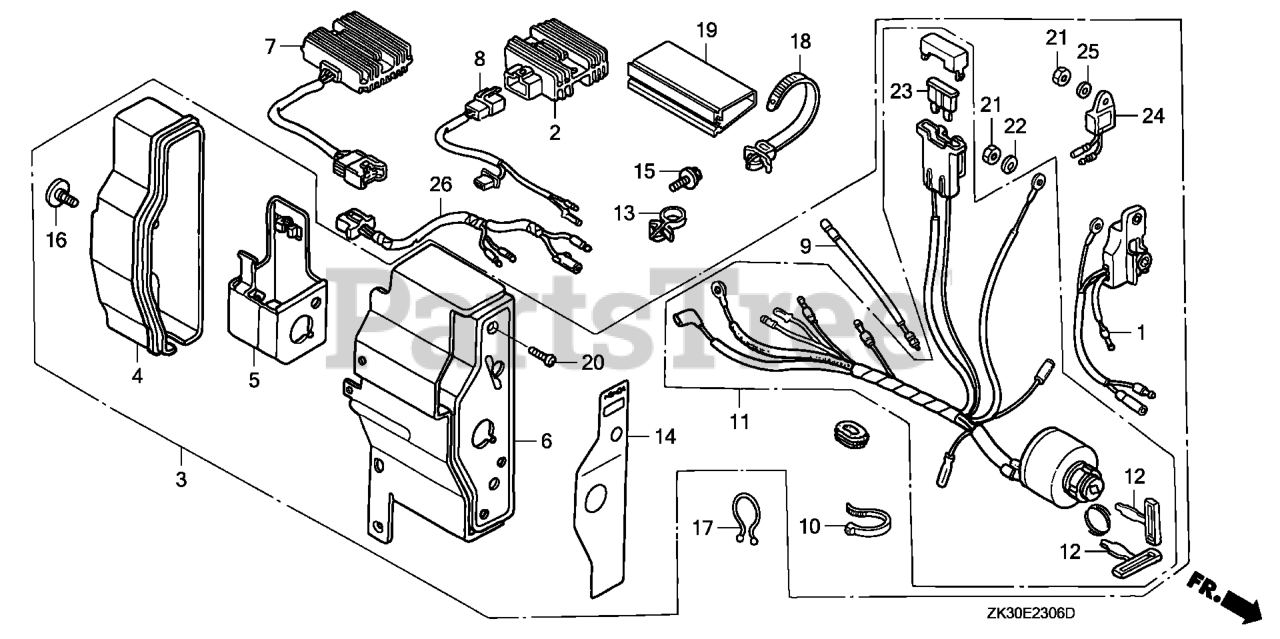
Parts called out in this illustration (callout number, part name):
3	BOX ASSY., CONTROL (18A) *R280* (EXP-ALERT) (POWER RED)
4	CASE, CONTROL
5	BRACKET, CASE MOUNTING
6	PANEL, CONTROL *R280* (POWER RED)
7	RECTIFIER ASSY., REGULATOR (20A)
9	SUB-WIRE HARNESS
10	BAND
11	SWITCH ASSY., COMBINATION (18A-CHARGE)
12	KEY
13	HOLDER, STOP SWITCH WIRE Use up to Engine SN 2056819.
14	MARK, CONTROL BOX (EXTERNAL-REGULATOR)
15	BOLT, FLANGE (6X12) (CT200)
16	SCREW, SPECIAL (6X12)
17	CLIP, PURSE LOCK
18	STRAP, CABLE (118MM) *NH1L* (Honda Code 1170653). (BLACK)
19	TUBE, FASTENER (30)
20	SCREW, PAN (4X12)
21	NUT, HEX. (4MM)
22	WASHER, SPRING (4MM)
23	FUSE, BLADE (25A)
24	ALERT UNIT, OIL
25	WASHER, PLAIN (4MM)
26	SUB-WIRE HARNESS ASSY.
